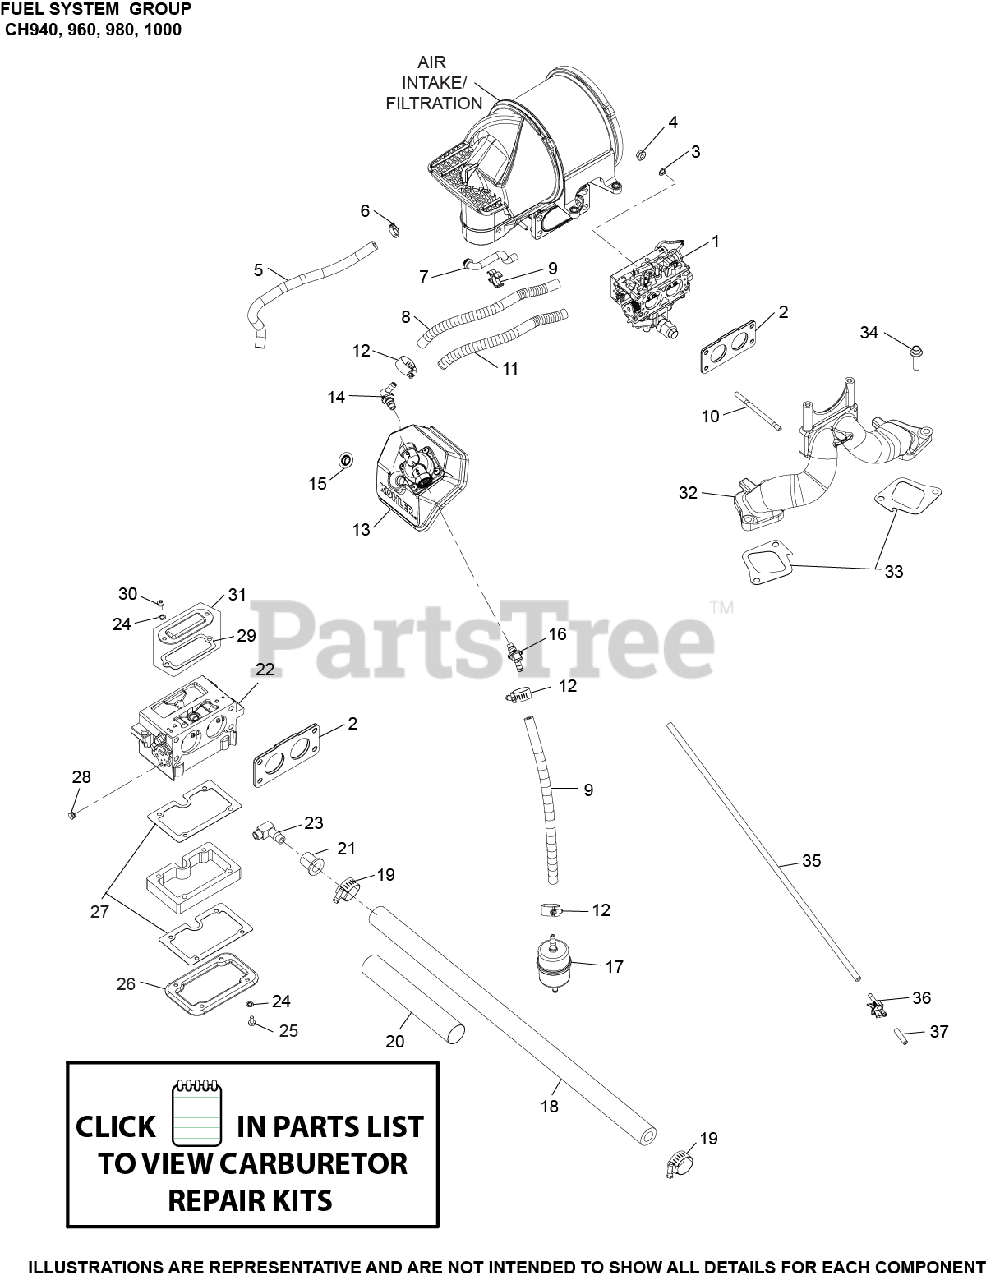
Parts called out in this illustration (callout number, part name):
1	KIT, CARBURETOR
2	GASKET, CARBURETOR - USE 24 041 82-S
3	WASHER, INT TOOTH LOCK 1/4"
4	NUT, FLG M6X1.0
5	HOSE, FUEL LOW PERMEATION
6	CLIP
8	HOSE,LW PERM.FUEL 24.00"-USE 25 111 81-S
10	STUD,M6X1.0X96
11	SLEEVE, ANTI ABRASION-USE 25 431 12-S
12	CLAMP, HOSE (KM)-USE 25 237 31-S
13	KIT, FUEL PUMP
14	KIT, 90 DEG. FITTING
16	KIT, 45 DEG. FITTING
17	FILTER, FUEL
34	SCREW, FLG M8X1.25X30
35	HOSE, EVAPORATIVE 20"
36	CONNECTOR, EVAPORATIVE
37	CAP, MASKING
